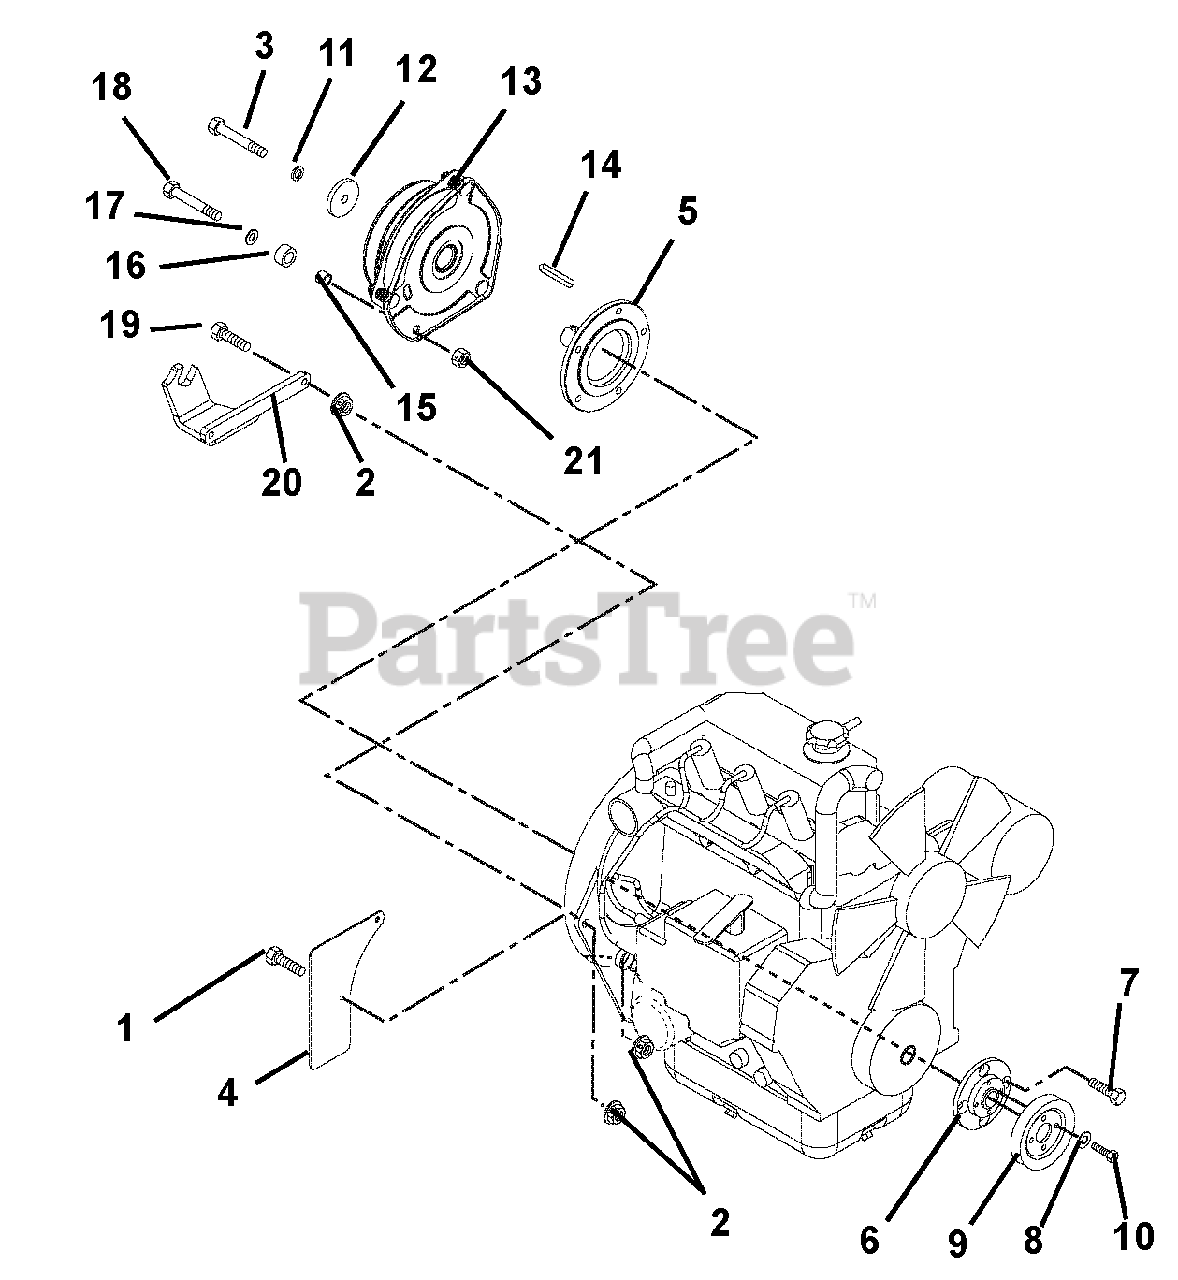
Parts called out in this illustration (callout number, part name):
1	Bolt, Hex .31 -18 x .75 Grade 5
2	Nut, Locking Top Flange .31-18
3	Bolt, Hex .44-20 x 2.50 Grade 5 YZ EP80
4	Guard, Flywheel
5	Stub Shaft
6	Adapter, Sheave
7	Bolt, M8 1.25 x 25
8	Washer, Locking .25 x .062
9	Sheave, Poly V 1.0 x 3.25
10	Bolt, Hex .25-20 x .75 Grade 5
11	Washer, Locking .44 x .109 Regular
12	Washer, Flat Steel .469 x 2.00 x .25
13	Clutch, Ogura
14	Key .25 x .25 x 2.25
15	Spacer .375 x .688 x .500
16	Bumper, Rubber .62 x 1.0 x .51
17	Washer, Flat Steel .406 x .812 x .065
18	Bolt, Hex .38-16 x 1.00 Grade 5
19	Bolt, Hex .31-18 x 1.25 Grade 5
20	Bracket, Clutch Stop
21	Nut, Hex Jam .375-16
